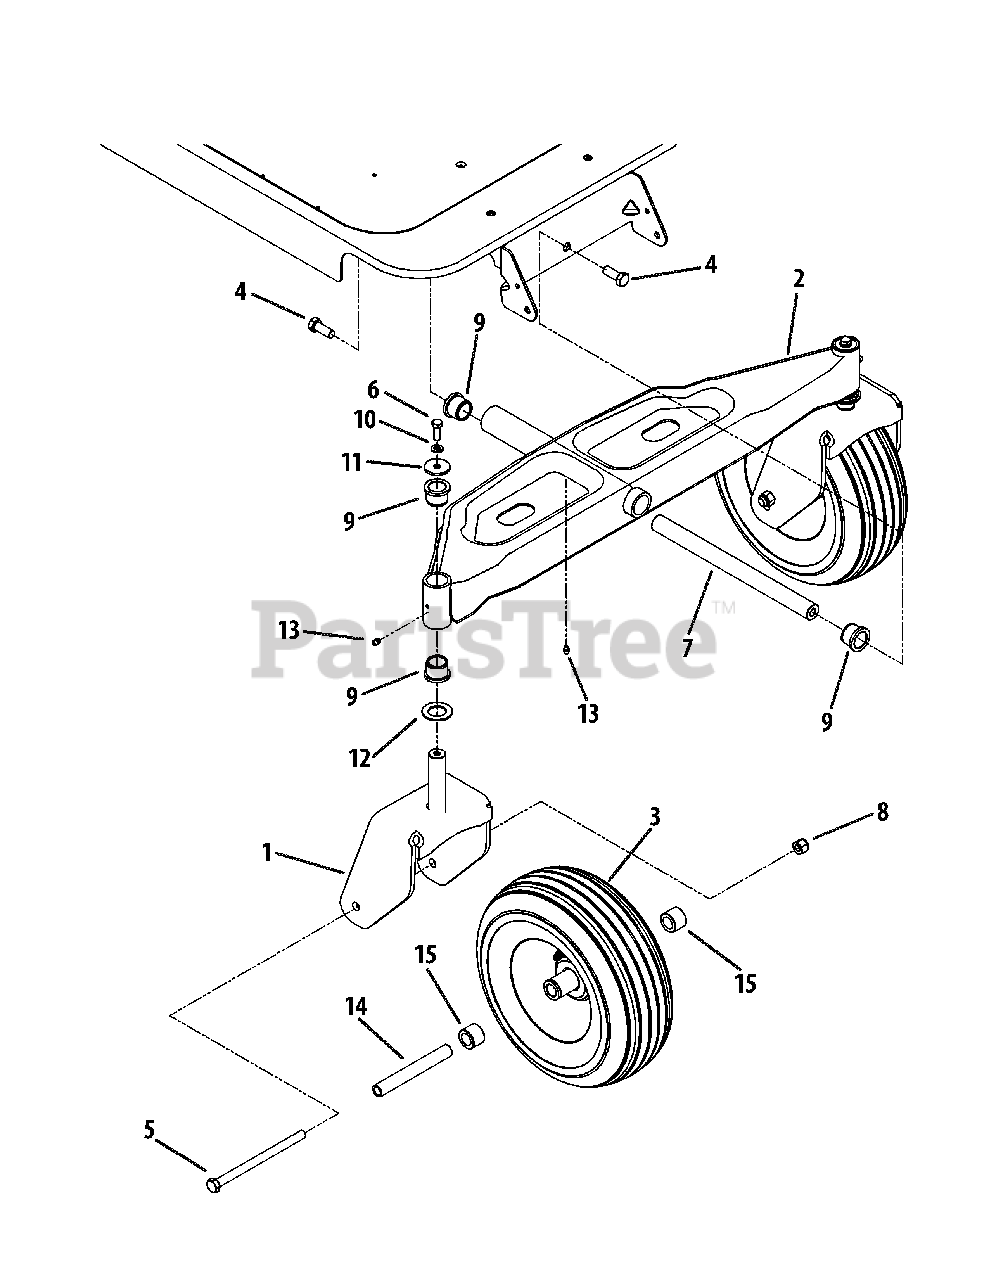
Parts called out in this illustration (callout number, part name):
1	Castor Wheel Bracket
2	Front Pivot Axle
3	Wheel Assembly, 13 x 5-6
4	Hex Lock Screw, 1/2-13 x 1.25
5	Hex Cap Screw, 1/2-20 x 7.25
6	Hex Cap Screw, 3/8-16 x 1.0
7	Axle Shaft
8	Hex Insert Lock Nut, 1/2-13
9	Flange Bearing, 1.0 x 1.246
10	Lock Washer, 3/8
11	Flat Washer, .39 x 1.5 x .134
12	Flat Washer, 1.0 x 1.75 x .10
13	Lube Fitting, 3/16 Drive
14	Spacer, .51 x .75 x 5.825
15	Hub, .76 x 1.23 x .92
